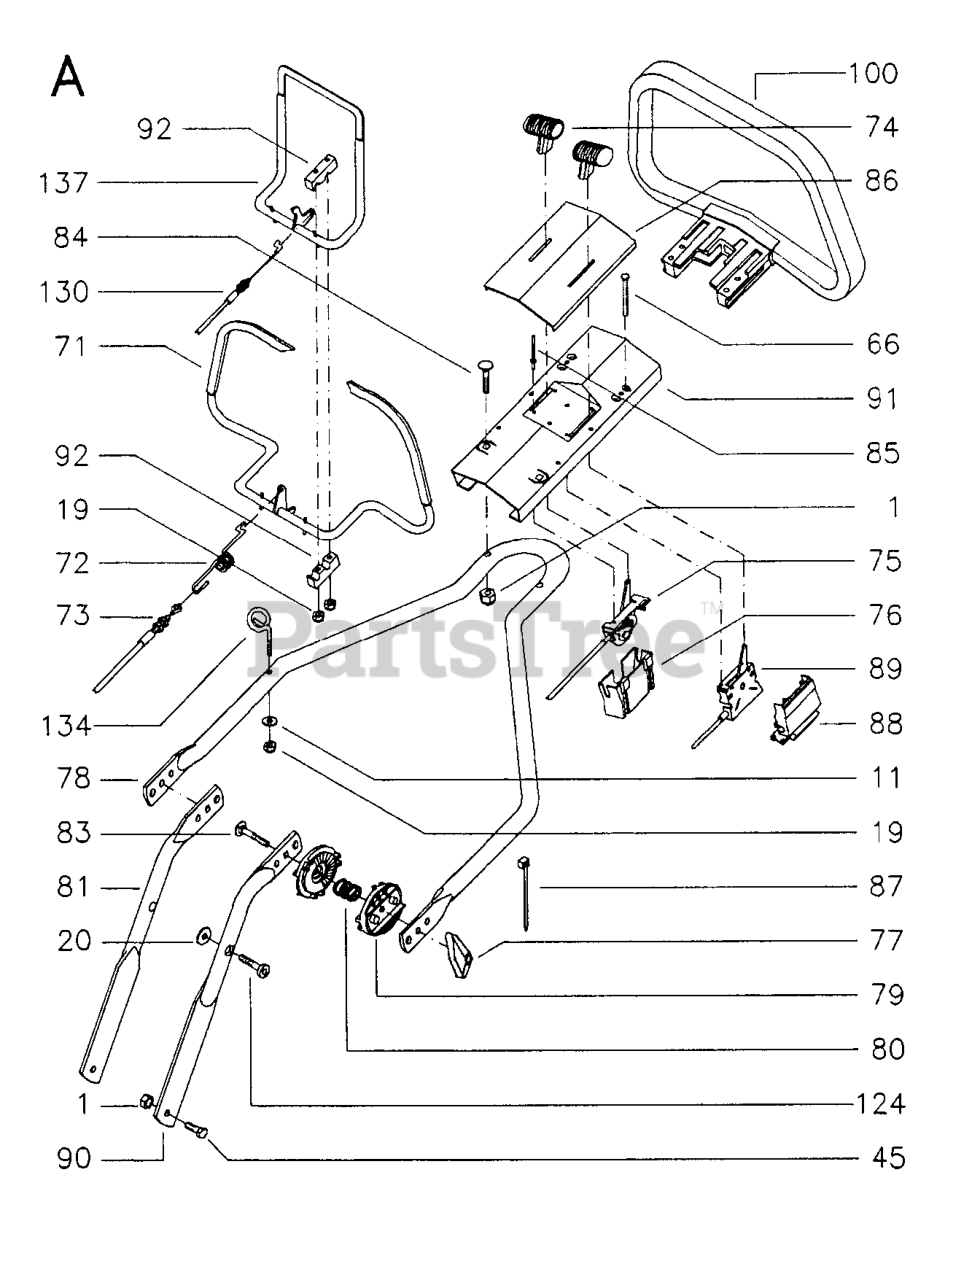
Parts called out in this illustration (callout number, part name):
1	LOCKNUT M8
19	LOCKNUT M6
45	SCREW M6S 8X25
75	WIRE R 53S/SE
77	WINGNUT
90	HANDLE
134	CABLE GUIDE
